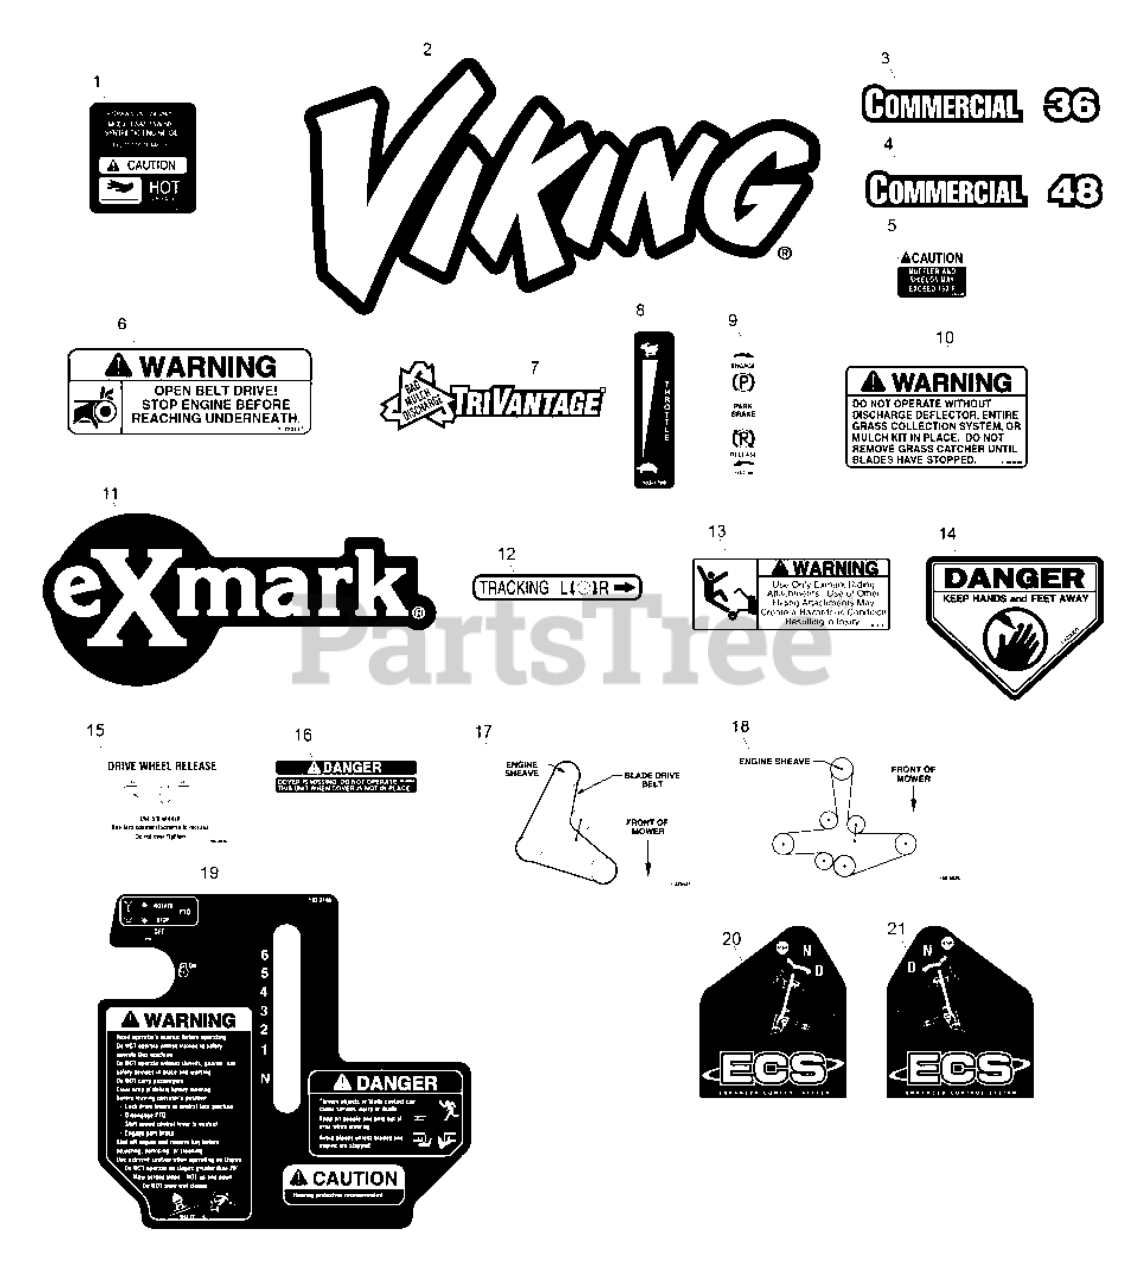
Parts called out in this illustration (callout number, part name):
2	DECAL,VH MODEL
3	DECAL,COMMERCIAL 36
4	DECAL,COMMERCIAL 48
6	DECAL,BELT DRIVE
8	DECAL,THROTTLE ONLY
9	DECAL-BRAKE, PARK
10	DECAL-WARNING, DISCHARGE
11	DECAL,EXMARK LOGO
12	DECAL,TRACKING ADJUST
13	DECAL,SULKY WARNING
14	DECAL-DANGER
15	DECAL,DRIVE RELEASE
16	DECAL-COVER, MISSING
17	DECAL,BELT ROUTING 32/36
18	DECAL,BELT ROUTING
19	DECAL,CONSOLE VH ECS
20	DECAL,LH ECS INSTRUCTION
21	DECAL,RH ECS INSTRUCTION
